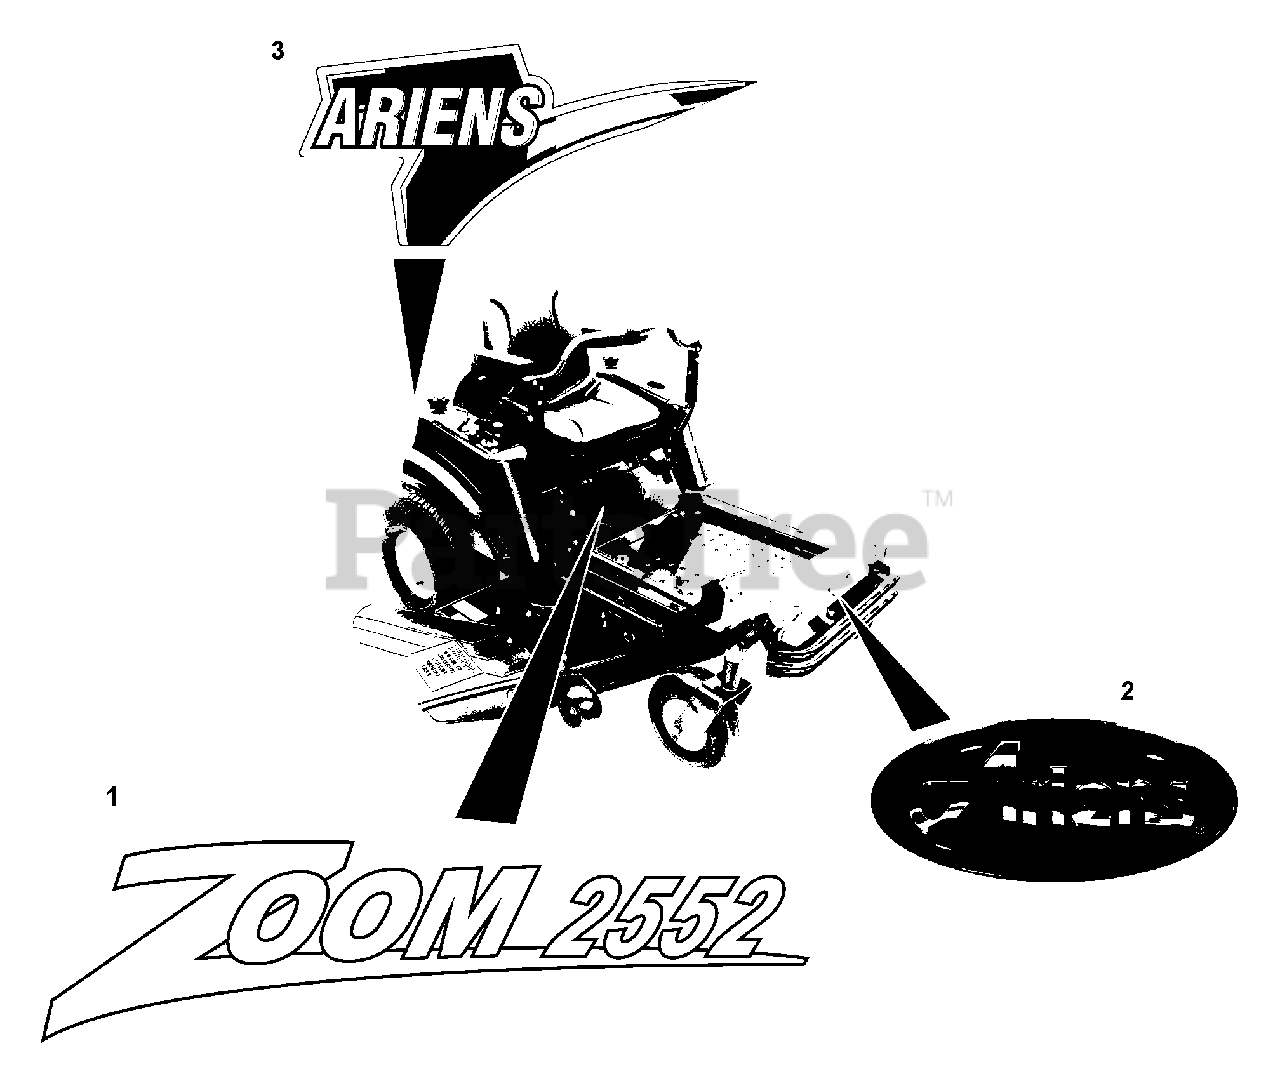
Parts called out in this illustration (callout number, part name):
1	DECAL, ZOOM 1640
2	DECAL-ARIENS JEWEL
3	DECAL, ZOOM HOOD
